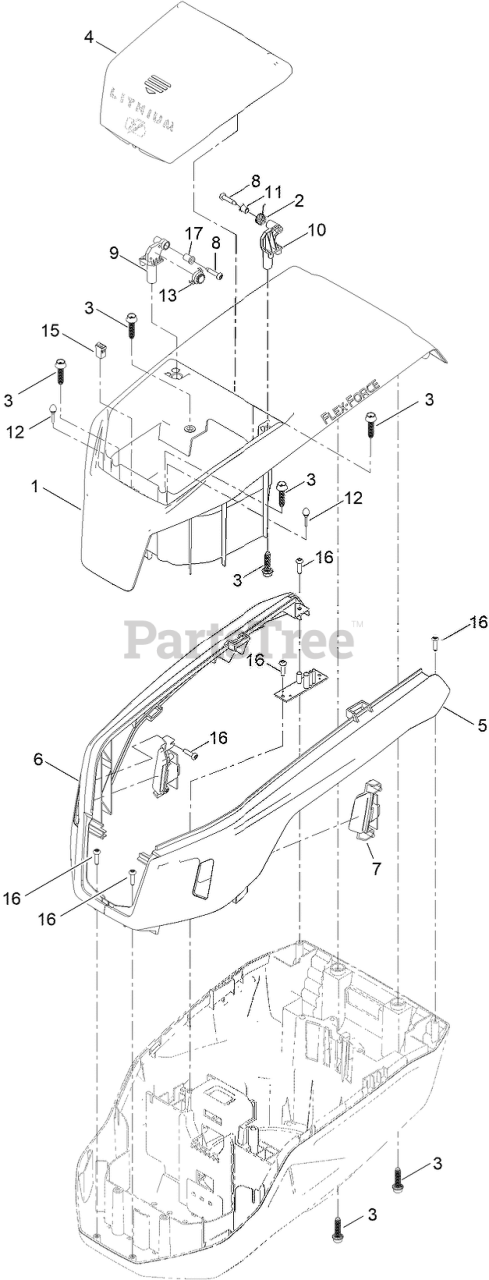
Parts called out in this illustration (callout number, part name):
1	SHROUD-UPPER
2	SPRING-TORSION
3	SCREW-FLANGE, PLASTIC
4	DOOR-BATTERY
5	BEZEL-LH
6	BEZEL-RH
7	LED ASM
9	PIVOT-DOOR, BATTERY
10	PIVOT-DOOR, BATTERY
11	BUSHING-SPACER
12	BUMPER-RUBBER
13	DAMPER-GEAR
15	LATCH-PUSH
16	SCREW-TORX DRIVE PLASTITE
17	BUSHING-SPACER, METAL
